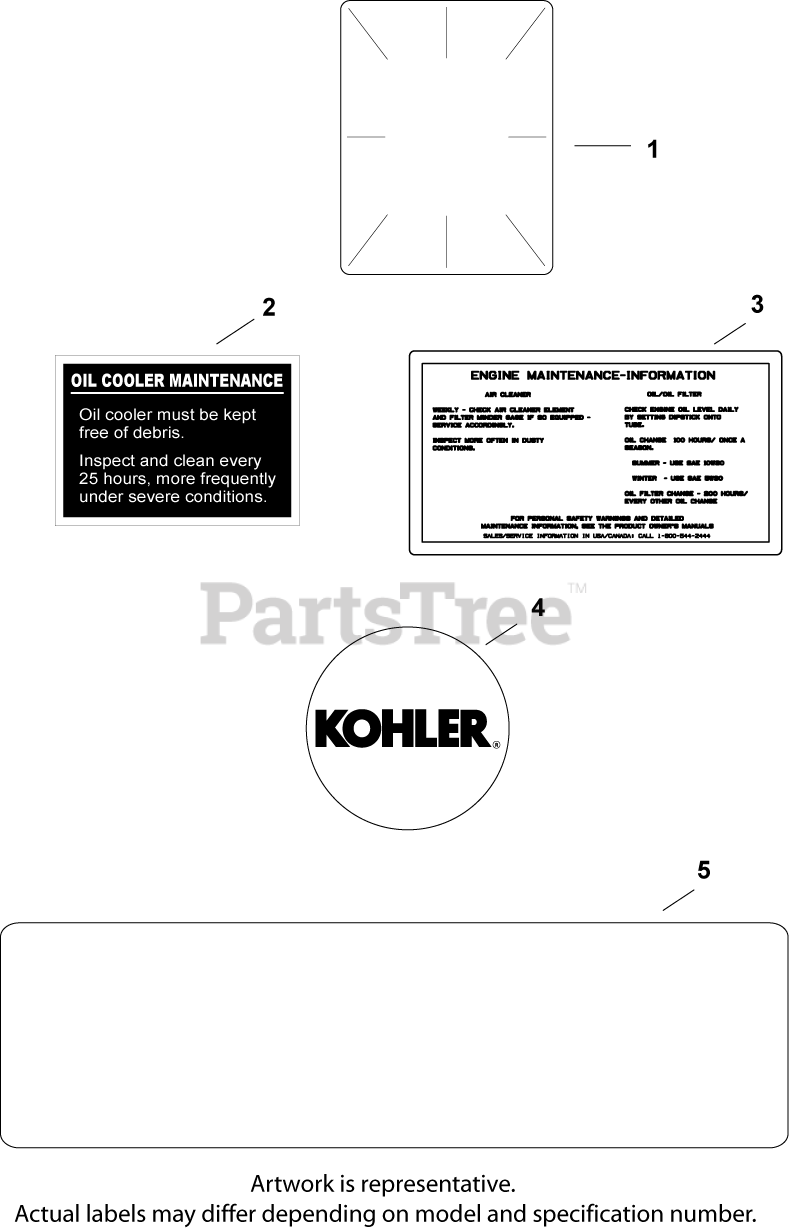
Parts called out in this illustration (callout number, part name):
1	DECAL, CLEAR LAMINATE USE 25 113 70-S
2	DECAL, OIL COOLER - (#DSC)
3	DECAL, AIR CLEANER - (#DSC)
4	LABEL, (ROUND KOHLER GOLD)-USE 24 113 18
5	DECAL, 25 HP
